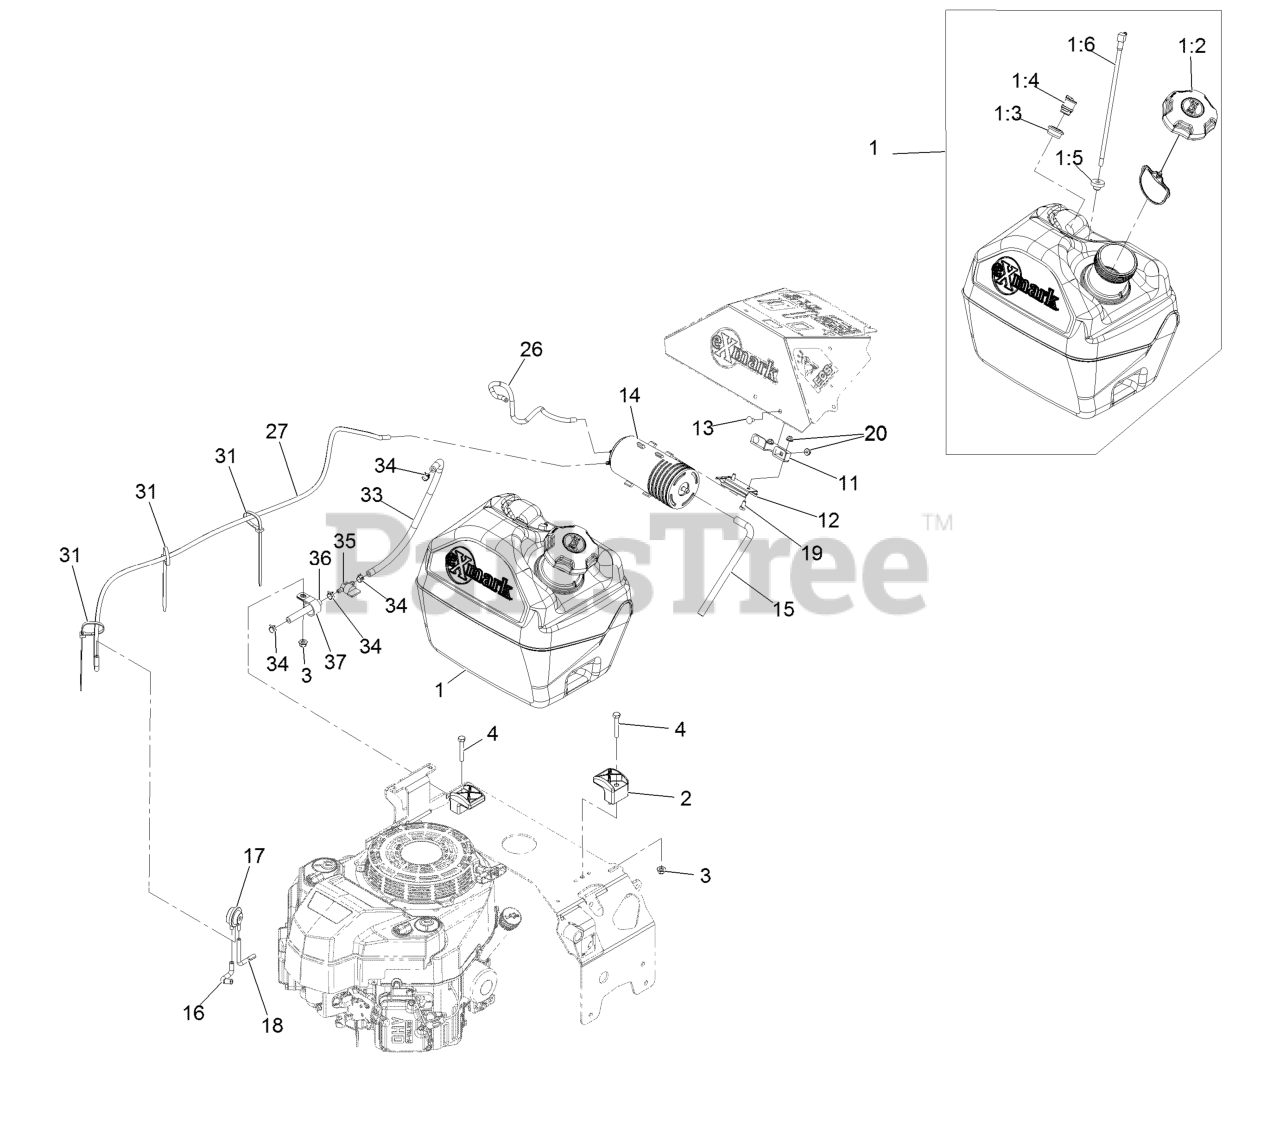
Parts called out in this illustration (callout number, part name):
1	ASM, Fuel Tank 5 Gal
1:2	Cap-Fuel, Ratcheting
1:3	Grommet
1:4	Valve-Vent, Fuel
1:5	Bushing
1:6	Fitting-Fuel (W/Line And Screen)
3	Nut-HF, NI
4	Screw-HH
11	Bracket-Canister, Carbon
12	Bracket-Canister, Carbon
13	Screw-CARR
14	Canister-Carbon, 800Cc
15	Hose-Vent, Canister
16	Hose-Vent, Formed
17	Valve-Control, Vacuum
18	Hose-Vent, Formed
19	Screw-HH
26	Hose-Emissions
27	Hose-Vent, Formed
31	Tie-Plastic
33	Hose-Fuel
34	Clamp-Hose
35	Valve-Fuel
36	Hose-Fuel
37	Clip-Loom
